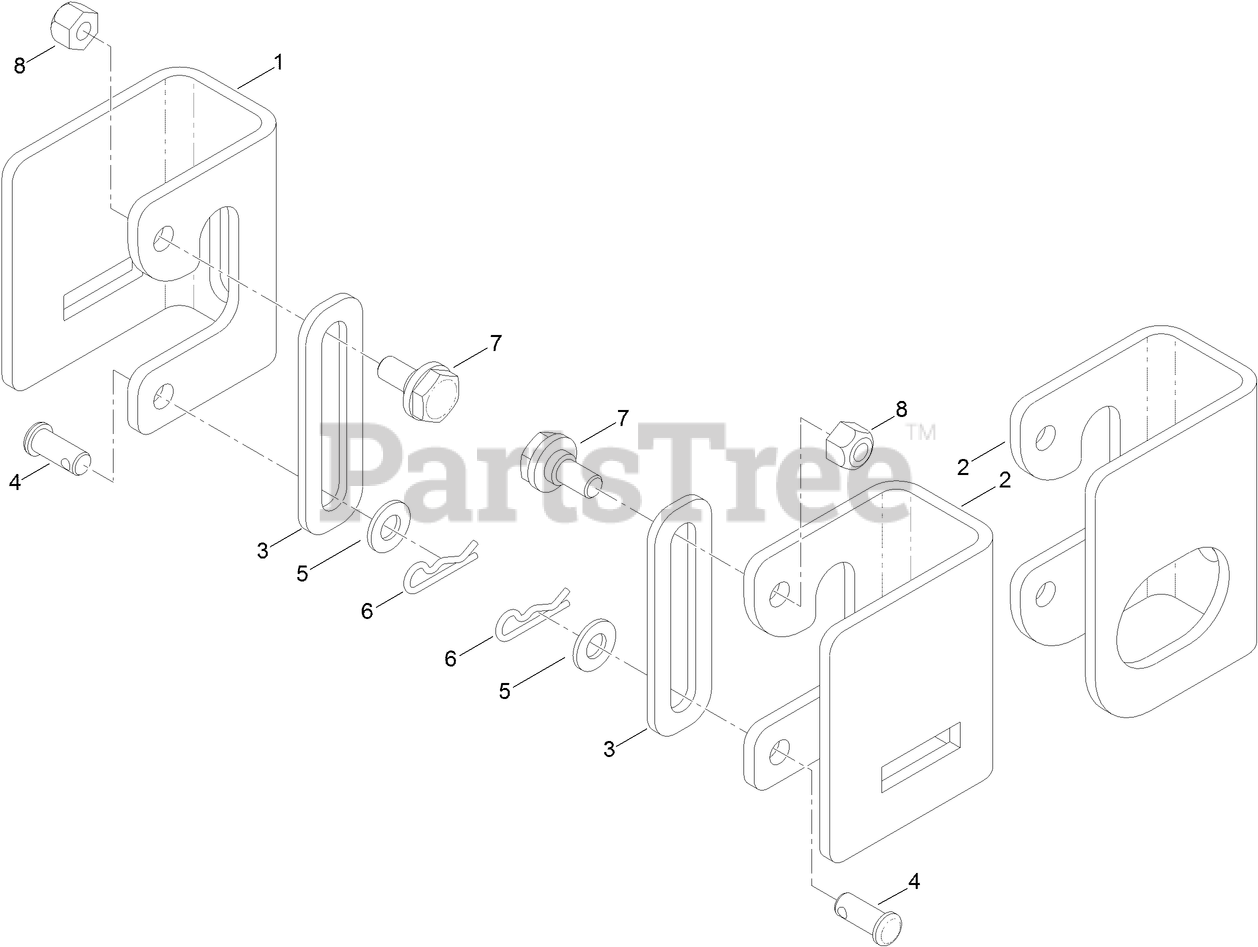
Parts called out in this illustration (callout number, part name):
1	BRACKET-HANGER, RH
2	BRACKET-HANGER, LH
3	LINK-RETENTION, DECK
4	PIN-CLEVIS
5	WASHER-PLAIN
6	PIN-COTTER
7	BOLT-SHOULDER
8	NUT-LOCK, NI
